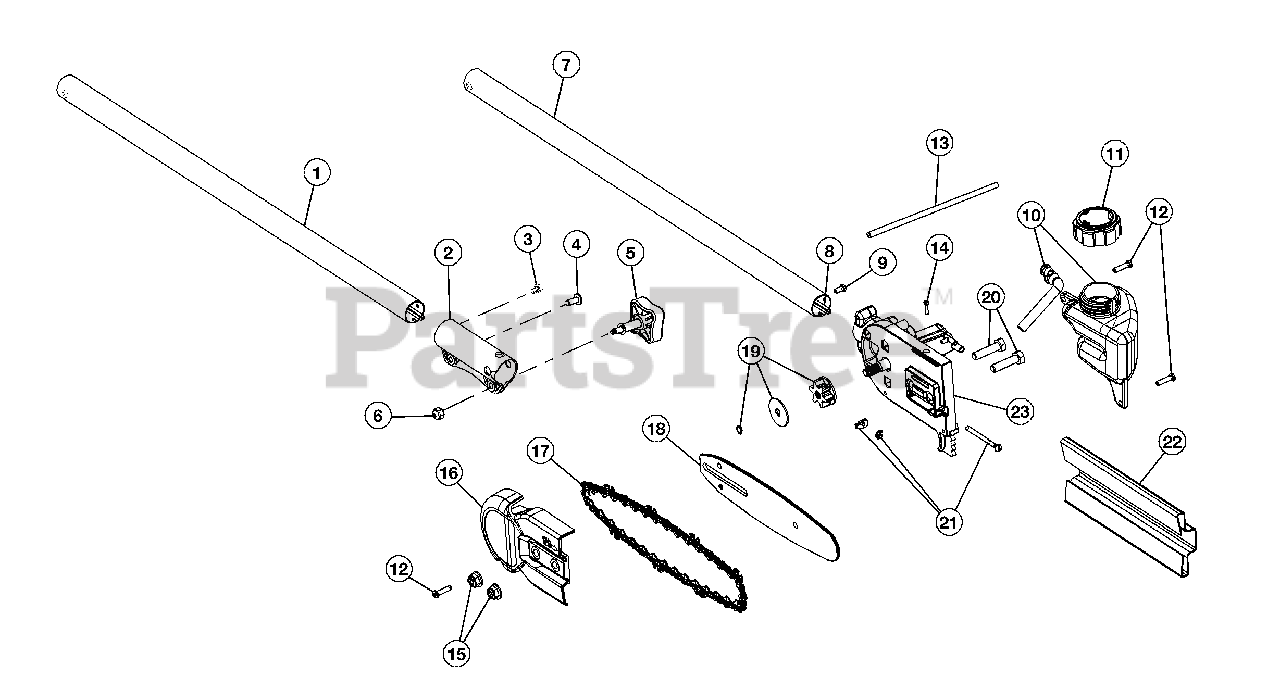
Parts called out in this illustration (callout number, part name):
1	Extension Boom
2	Split Boom Coupler (Incl. 3-6)
5	Adjustment Knob
6	Knob Retaining Nut
7	Drive Shaft Housing (Incl. 8)
8	Flexible Drive Shaft
9	Screw
10	Oil Tank Assembly
11	Fuel Cap Assembly
13	Oil Line
16	Chain Guard
19	Sprocket Assembly
21	Chain Tension Hardware Assembly
22	Chain Cover
23	Gearbox Assembly (Incl. 14 & 19)
